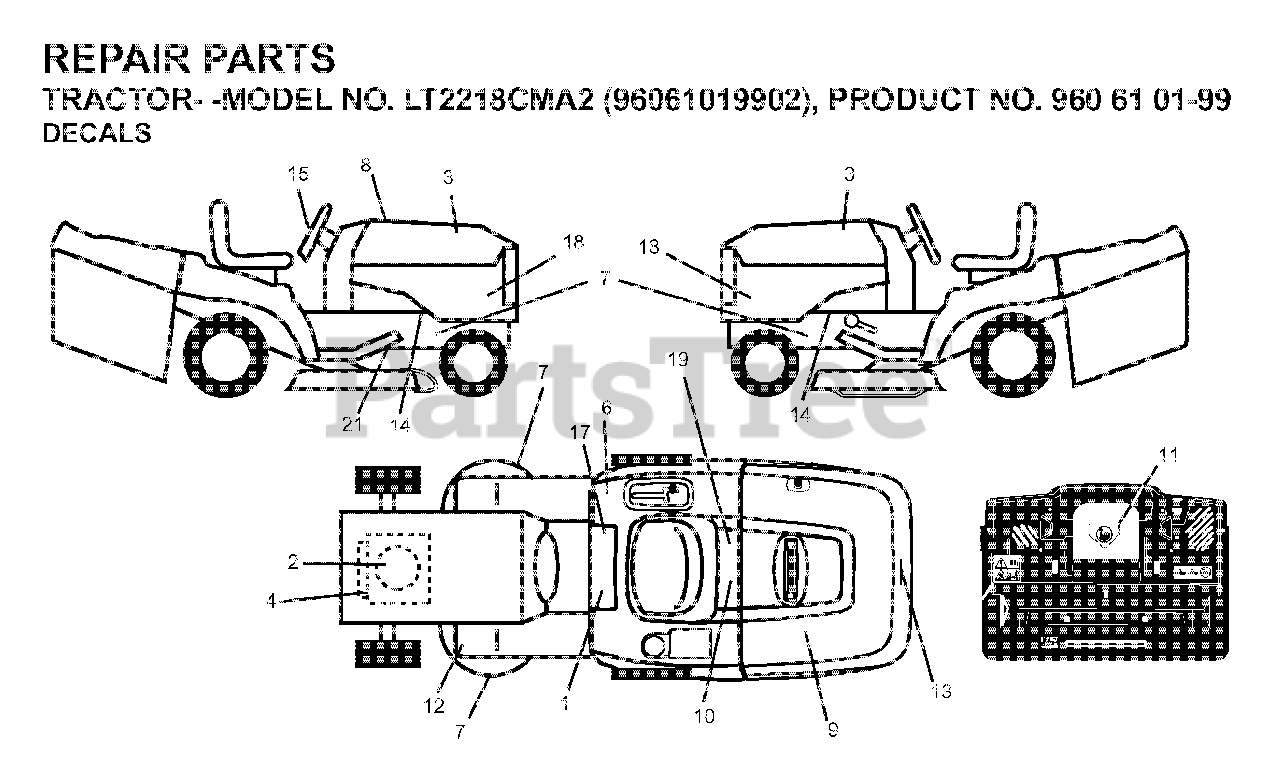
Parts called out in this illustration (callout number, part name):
10	DECAL BTRY SYMBOLS
11	DECAL.INTERNATIONL.CUTFINGER
17	DECAL PARK BRAKE
19	DECAL PARK BRAKE
